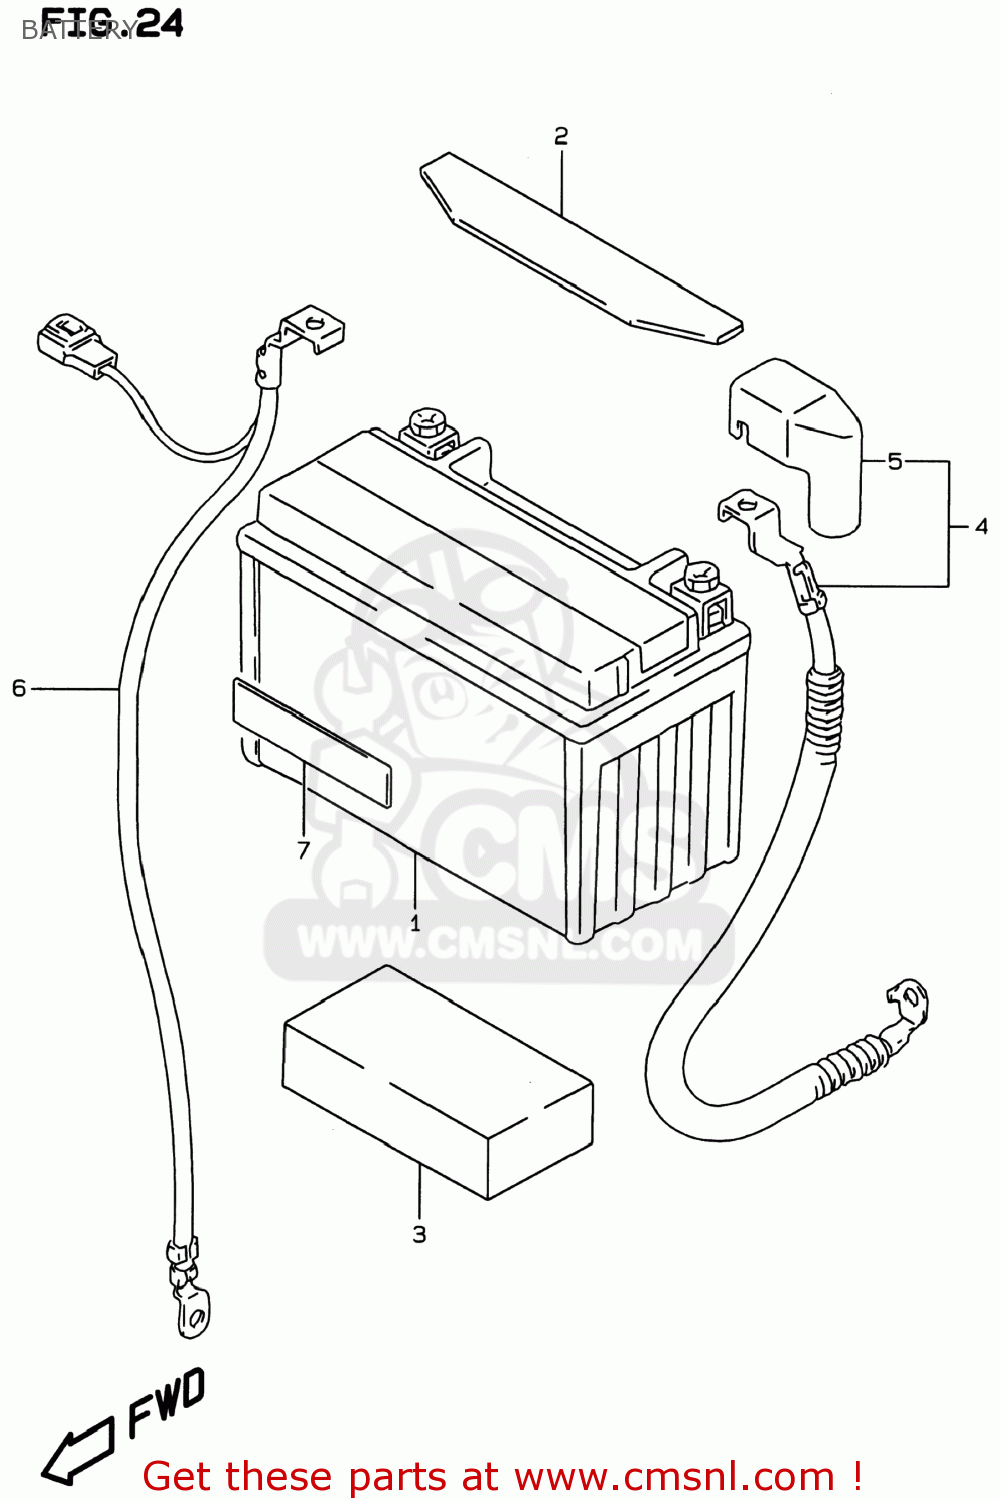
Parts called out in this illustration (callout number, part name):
1	BATTERY ASSY(YTX9-BS,12V8AH)
2	PROTECTOR,BATTERY
3	CUSHION,BATTERY
4	WIRE,BATTERY PLUS LEAD
5	CAP,BATTERY PLUS TERMINAL
6	WIRE,BATTERY MINUS
7	PROTECTOR(20X90)X1.0
